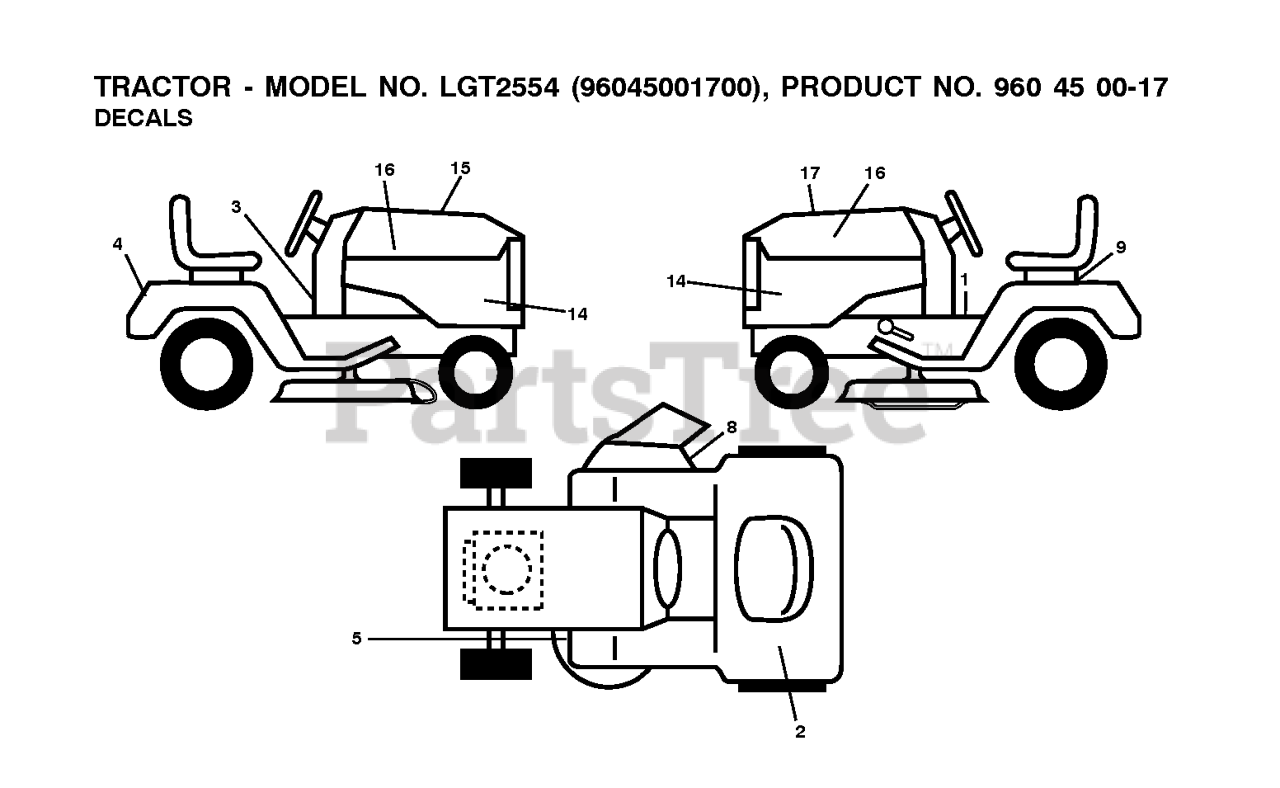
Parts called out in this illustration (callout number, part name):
1	DECAL.WARN.START.INSTRUCTIONS
2	DECAL,ETHANOL E85 WARNING
3	DECAL, WARNING SPARK ARRESTOR
4	DECAL.FENDER
5	DECAL.MOWER
8	DECAL.MOWER.SCH.48/54
9	DECAL BTRY SYMBOLS
14	DECAL.PNL.SD.LGT2554.KOHL.
15	DECAL.WARNING.CUST.RESP.E85.
16	DECAL.HOOD.LOGO.ORANGE.HUSQVAR
